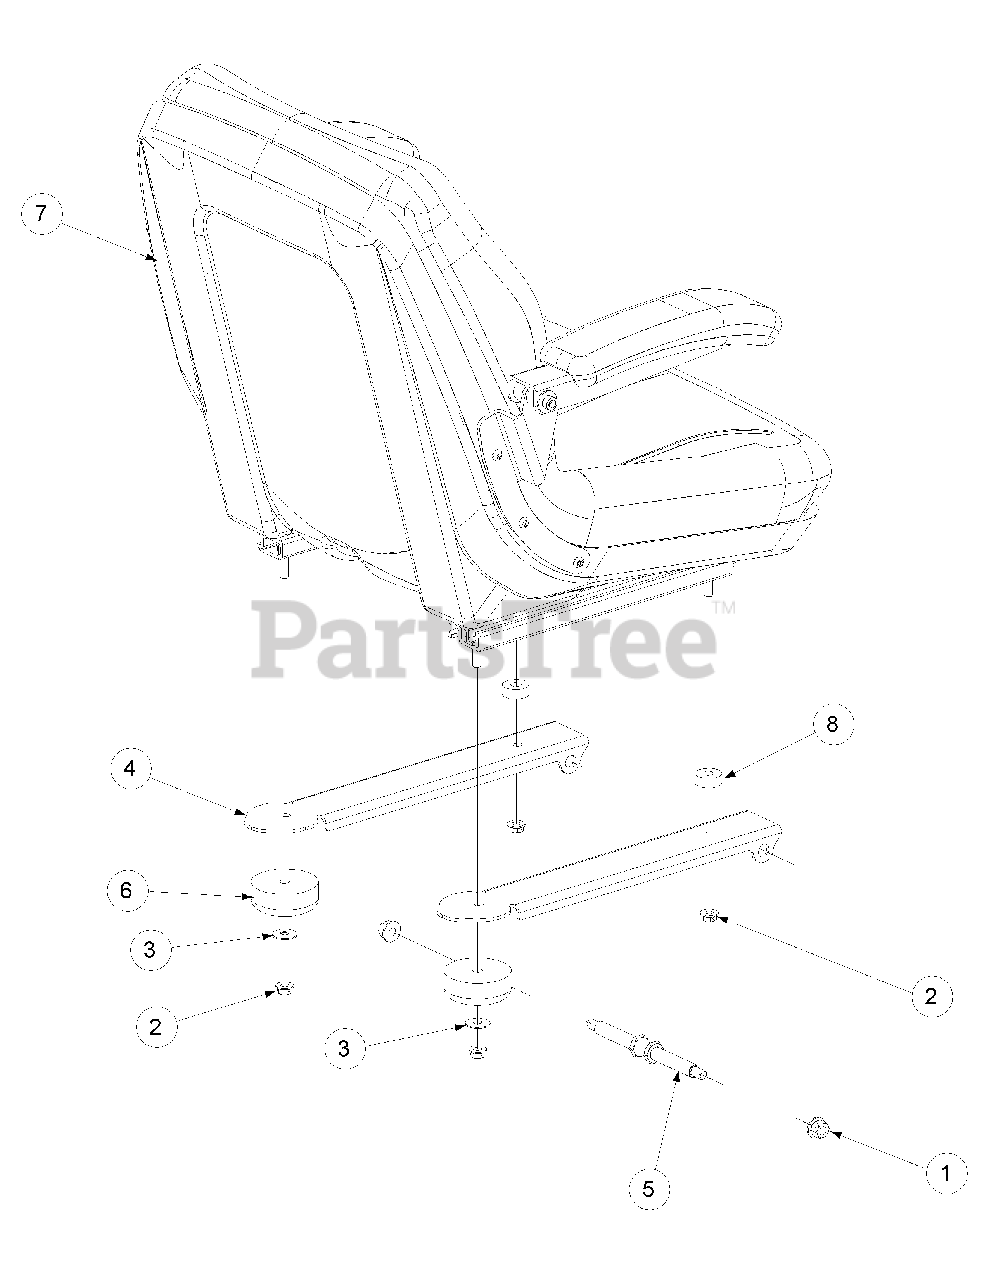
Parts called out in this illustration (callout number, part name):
1	Nut, Hex 3/8-16 Flange Lock
2	Lock Nut, Hex Flange, 5/16-18
3	Flat Washer, .406 ID, 1.00 OD, .105
4	Mounting Bracket, Seat
5	Shoulder Screw, .50x2.345, 3/8-16
6	Grommet, 2.5 OD x 1.0 Long
7	Adjustable Seat, Black
8	Spacer, .406 ID x 1.00 OD x .38
